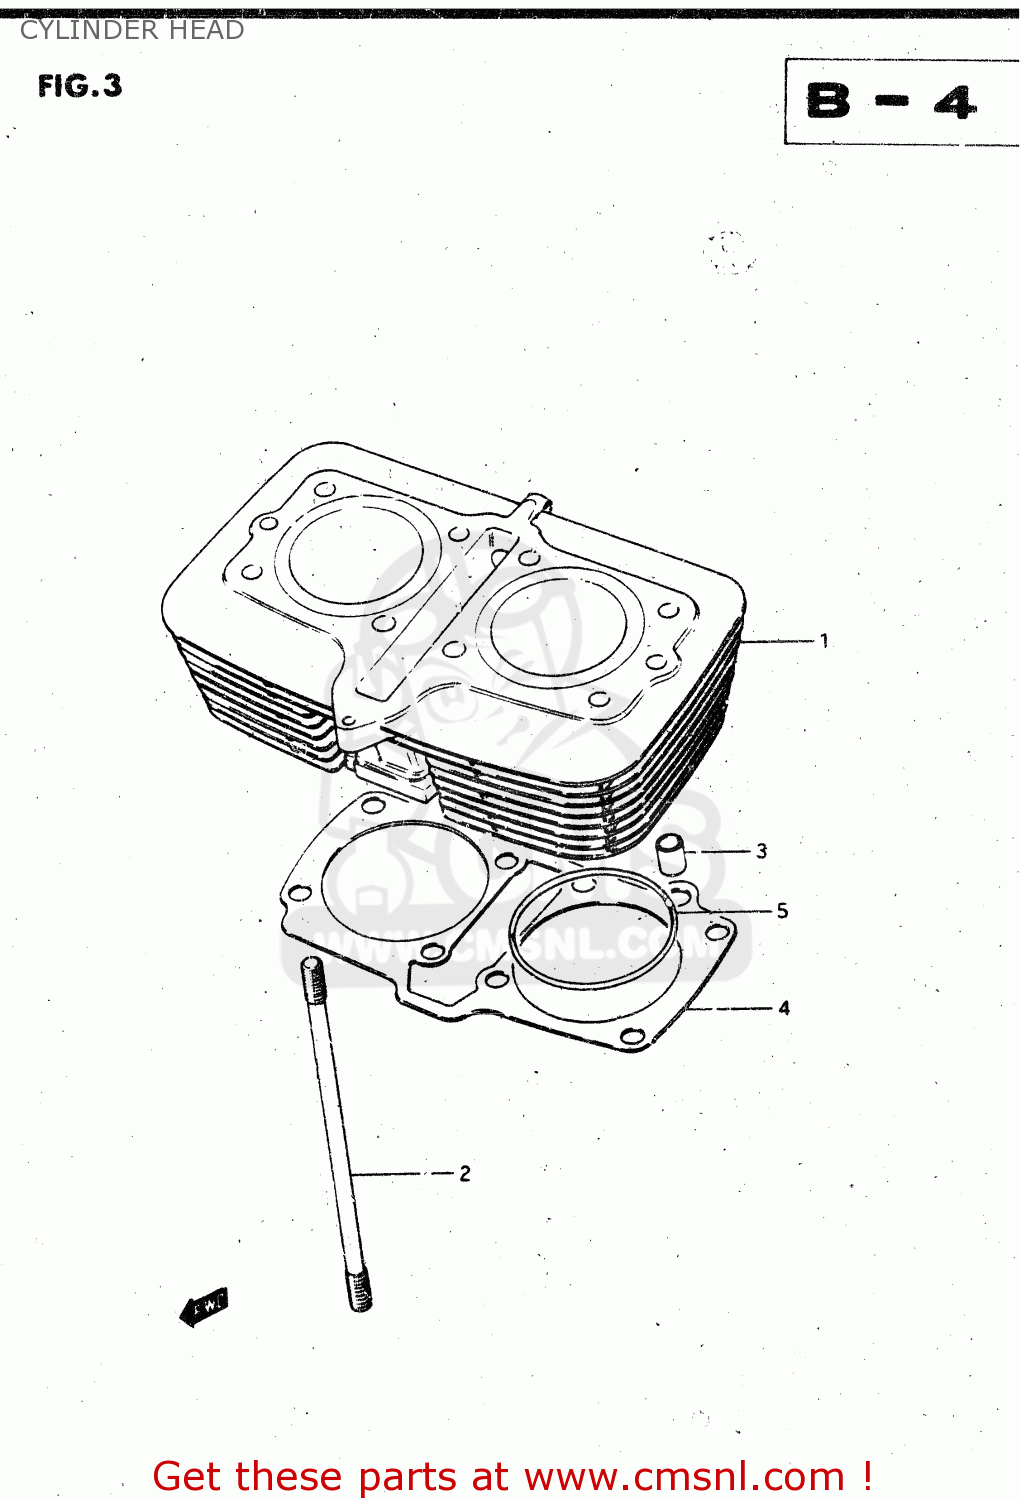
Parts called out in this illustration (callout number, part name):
1	HEAD ASSEMBLY,CYLINDER
2	GUIDE,INTAKE VALVE
3	GUIDE,EXHAUST VALVE
4	RING,SNAP
5	BOLT(6X39)
6	PIN(6.2X8X11)
7	BOLT
8	GASKET (NAS)
9	GASKET,CYLINDER HEAD (MCA)
10	BOLT
11	PIN
12	NUT
13	GASKET(10.5X22X2) (NAS)
14	SCREW
15	GASKET(5.3X9.3X1.2) (NAS)
16	PLUG
17	PAD,CYLINDER HEAD
18	PAD
19	PAD,CYLINDER
20	SPARK PLUG
21	GEAR,TACHOMETER DRIVEN
22	O-RING (D:2.4 ID:39.7)
23	SEAL,TACHOMETER DRIVEN
24	SEAL,OIL(5X12X8)
25	PLATE,TACH DRIVE GEAR SLEEVE
26	SCREW(5X12)
27	PIPE,INTAKE
29	SCREW
30	LOCK WASHER
31	CLAMP
